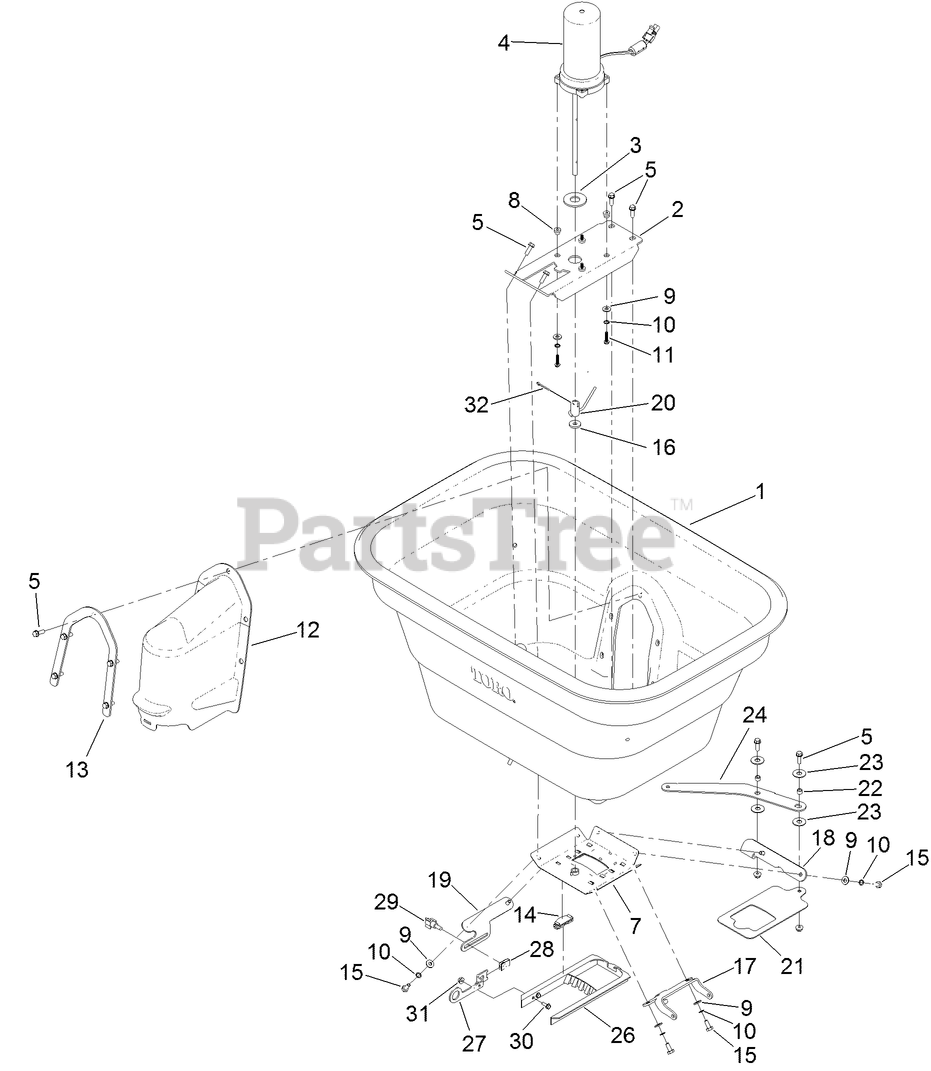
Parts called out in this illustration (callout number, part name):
1	HOPPER-SPREADER
2	MOUNT-MOTOR
3	SPACER
4	MOTOR-SPREADER
5	SCREW-HWH
7	GATE-BEARING
9	WASHER-FLAT
10	WASHER-LOCK, INT
11	SCREW-SHWH
12	COVER-MOTOR
13	SUPPORT-COVER
14	GUIDE-RATE, GATE
15	SCREW-HH
16	WASHER-FELT
17	MOUNT-DEFLECTOR
18	MOUNT-GATE, PIVOT
19	MOUNT-GATE, PIVOT
20	WELD-AGITATOR
21	GATE-SPREADER, SEED
22	SPACER
23	WASHER
24	ARM-ENGAGEMENT
26	DIFFUSER
27	BRACKET-ACCUWAY, SLIDE
29	KNOB-STAR, THREE
31	NUT-LOCK, FLANGE
32	PIN-COTTER
